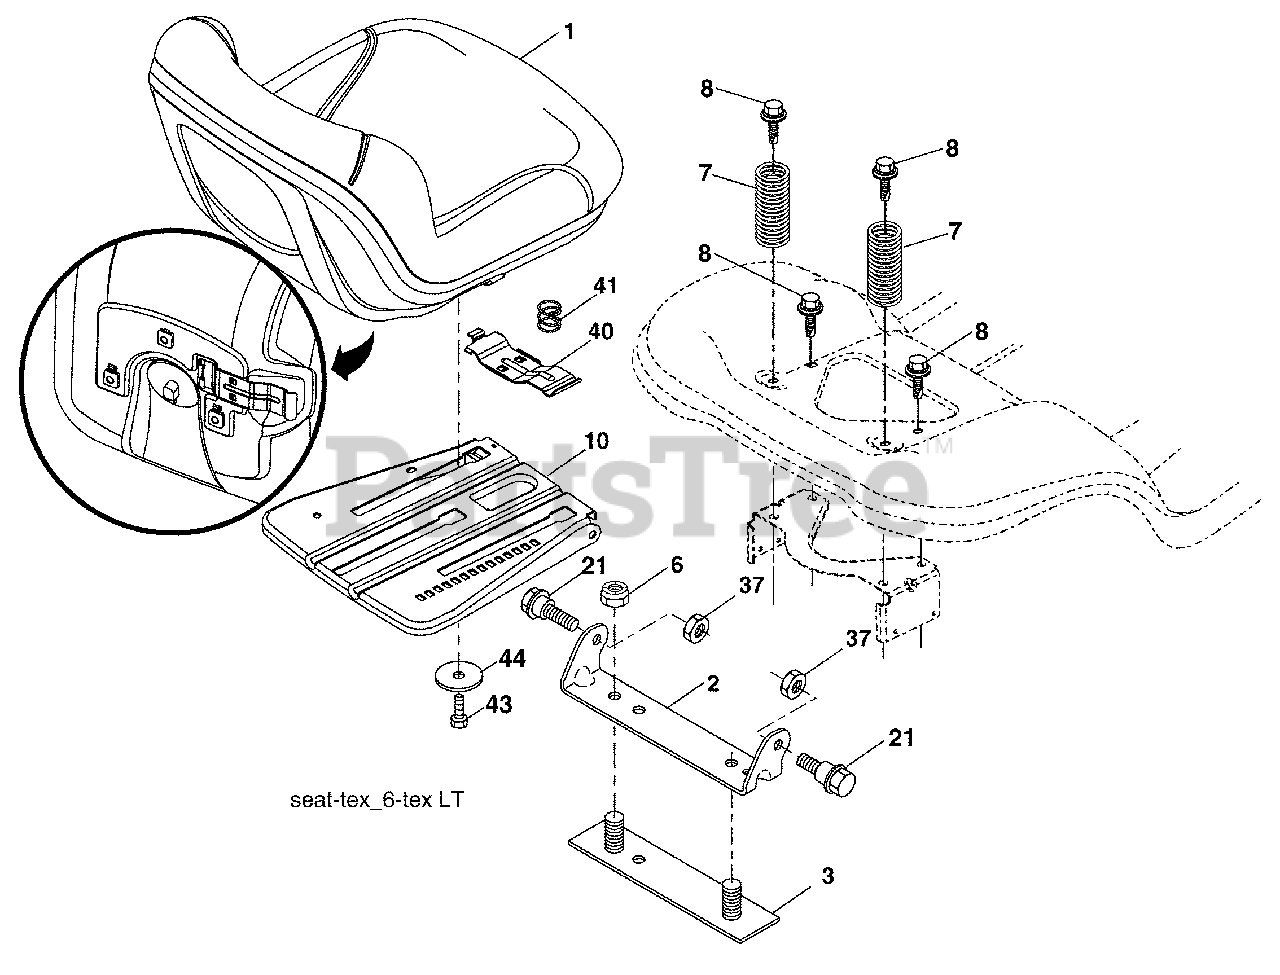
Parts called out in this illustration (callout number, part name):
1	Seat
2	Bracket Pivot Fender
3	Strap, Asm Fender
5	Clip, Push In, Hinged
6	Nut, Lock W/Ins. 3/8-16 unc
7	Spring, Seat Cprsn
8	Bolt 5/16-18 uncx 3/4 w/Sems
10	Pan, Seat
21	Bolt, Shoulder 5/16-18
37	Nut, Lock 5/16-18 unc
40	Handle Slide Seat
41	Spring Latch Seat
43	Bolt Fin Hex 3/8-16 unc x 3/4
44	Washer 13/32 x 2-3/8 x 12 Ga.
